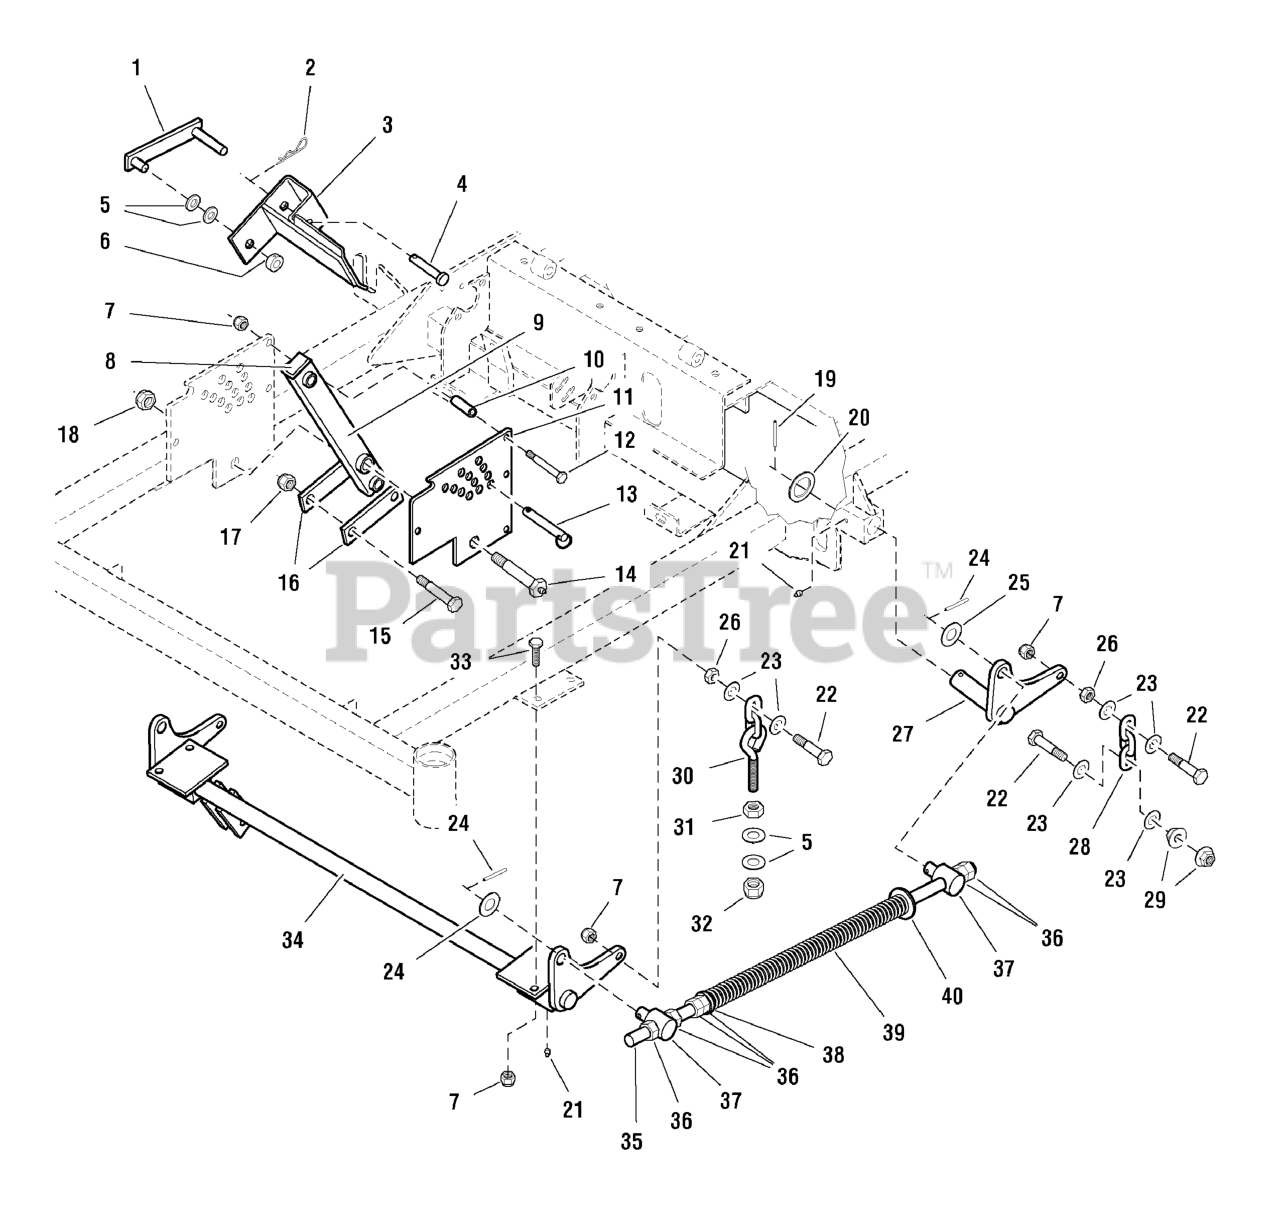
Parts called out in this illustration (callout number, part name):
1	DECK LIFT LOCK
2	HAIRPIN CLIP
3	WELD, DECK LIFT PEDAL
4	PIN, Clevis, 1/2 x 2-1/2
5	WASHER, 1/2 SAE
6	COLLAR, Split, 1/2
7	NUT, 3/8-16 HEX NYLON LOCK
9	ARM, Deck Lift Pivot
10	SPACER, .38 x .50 x 1.56
11	DECK HEIGHT PLATE
12	BOLT, 3/8-16 X 2-3/4" GD5 CZ
13	PIN, 1/2 x 3-1/2 w/ Lanyard
14	LIFT PIVOT BOLT
15	BOLT, 1/2-20 x 3
16	LINK, Deck Lift
17	NUT, Hex, Nylon Lock, 1/2-20
18	NUT, 5/8-11 Hex Jam Nylon Lock
19	PIN, Roll, 3/16 x 1-1/2
21	GREASE FITTING
22	BOLT, 3/8-16 X 1-3/4" GD5 CZ
23	WASHER, 3/8 SAE
24	PIN, Spring, 3/16 x 1-1/4
25	WASHER, 5/8" SAE
26	NUT, 3/8-16 HEX JAM
27	DECK LIFT PIVOT-LH
28	CHAIN, 3 LINKS
29	NUT, 3/8-16 Hex Serrated Flange
30	HANGER, FRONT DECK-2LINK, 5.5" EB
31	NUT, 1/2-13 Hex
32	NUT, 1/2-13 HEX NYLON LOCK
33	BOLT, 3/8-16 X 1-1/4" GD5 CZ
34	DECK LIFT SHAFT & MOUNT ASSEMBLY
35	SPRING ROD
36	NUT, 5/8-11 Hex
37	SPRING ROD PIVOT
38	SPACER, .63 x 1.06 x .23
39	SPRING, Deck Lift
40	WASHER, 5/8" USS
